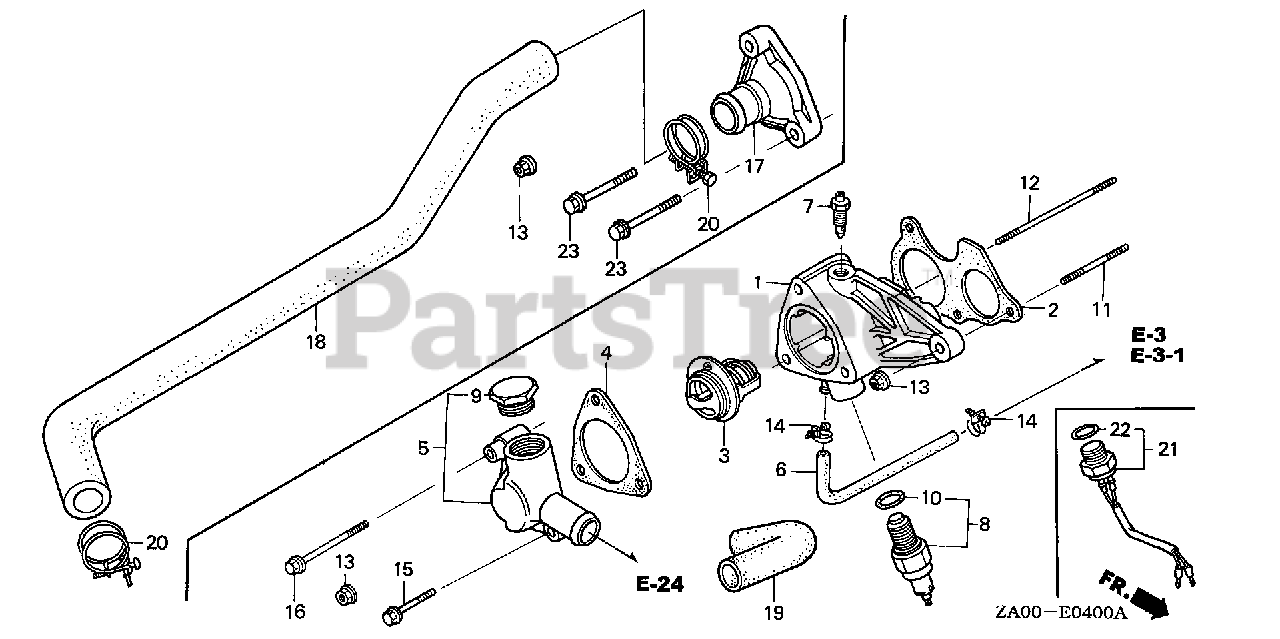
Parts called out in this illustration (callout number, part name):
1	CASE, THERMOSTAT
2	GASKET, GOVERNOR CASE
3	THERMOSTAT ASSY.
4	GASKET, THERMOSTAT COVER
5	COVER, THERMOSTAT
6	HOSE, WATER BYPASS
7	BOLT, BREATHING WATER
8	SWITCH ASSY., THERMOSTAT
9	BOLT, SEALING (25MM)
10	O-RING (13.5X1.4)
11	BOLT, STUD (6X25)
12	BOLT, STUD (6X60)
13	NUT, FLANGE (6MM)
14	CLIP, TUBE (D12.5)
15	BOLT, FLANGE (6X65)
16	BOLT, FLANGE (6X90)
